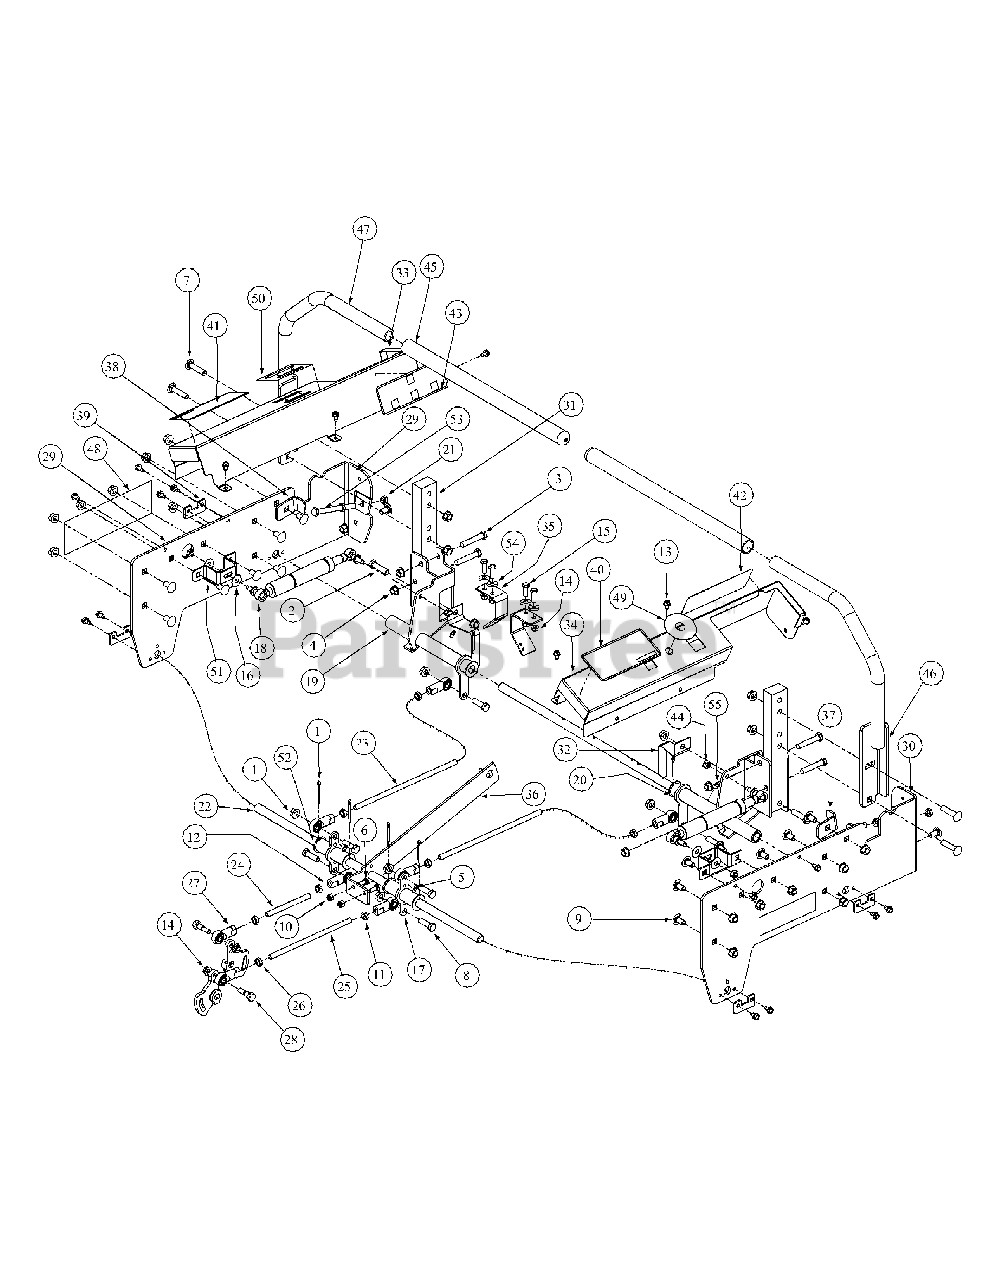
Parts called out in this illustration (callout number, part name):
1	Cotter Pin 5/32 x 1-1/2
2	HHCS, 3/8-16, 2.00
3	HHCS, 3/8-16, 2.25
4	Hex Nut, 3/8-16, Lock Flange
5	Grease Fitting, 1/4-28 x 3/16
6	HHCS, 1/4-20, .620
7	Hex Carriage Screw, 3/8-16, 1.75
8	HHCS, 3/8-16, 1.25
9	Carriage Bolt, 3/8-16 x .75
10	Lock Hex Nut, 1/4-20
11	Hex Jam Nut, 3/8-24
12	B/Joint, 3/8-24, Right Hand Female
13	Screw, TT, 1/4-20, 0.5, Hex Index
14	Nut, Lock, Hex Flange, 5/16-18
15	Hex, Cap Screw, 5/16-18 x 3/4
16	Belle Washer, .325 x .930 x .045
17	Belle Crank Assembly
17	Bushing
18	Cylinder Return to Neutral
19	Hub Assy, Control LH Bearing
19	Bearings
20	Hub Assy, Control RH Bearing
20	Bearings
21	Nut, 3/8-16, Jam
22	Shaft Mounting Belle Crank
23	Rod Connector 3/8 OD x 10.125
24	Rod Connector, 3/8 OD x 4.28 LG LH
25	Rod Connector, 3/8 OD x 8.06 LG RH
26	Nut, 3/8-24, Jam, LH Third
27	B/Joint, 3/8-24, LH Female
28	Screw, Shoulder Control Rod
29	Mounting Shaft, Control, Left
30	Mounting Shaft, Control, Right
31	Mounting Handle
32	Lever, Safety Switch
33	Control Panel, LH
34	Control Panel, RH
35	Switch Mounting Bracket, MMZ Lapbar
36	Link Mounting Control Shaft, Bracket
37	Stop, RH
38	Stop, LH
39	Holder Shaft, Park Brake
40	Decal MMZ, Right Hand Console
41	Decal, Left Hand Console
42	Decal Right Hand Control
43	Decal, Left Hand Control
44	Nut, Hex, Center Lock, M8
45	Grip, 1.0
46	Lapbar, Weldment, Right Handle
47	Lapbar, Weldment, Left Handle
48	Side Label, MTD Pro
49	Label, Ignition, 2.5 Diameter
50	Label, Control, Throttle and Choke
51	Bracket Assembly, Mount Dampener
52	Flat Washer, 5/8 Nylon
53	HHCS, 3/8-16, 3.00
54	Flat Washer, 5/16
55	Grease Fitting, 90°.
